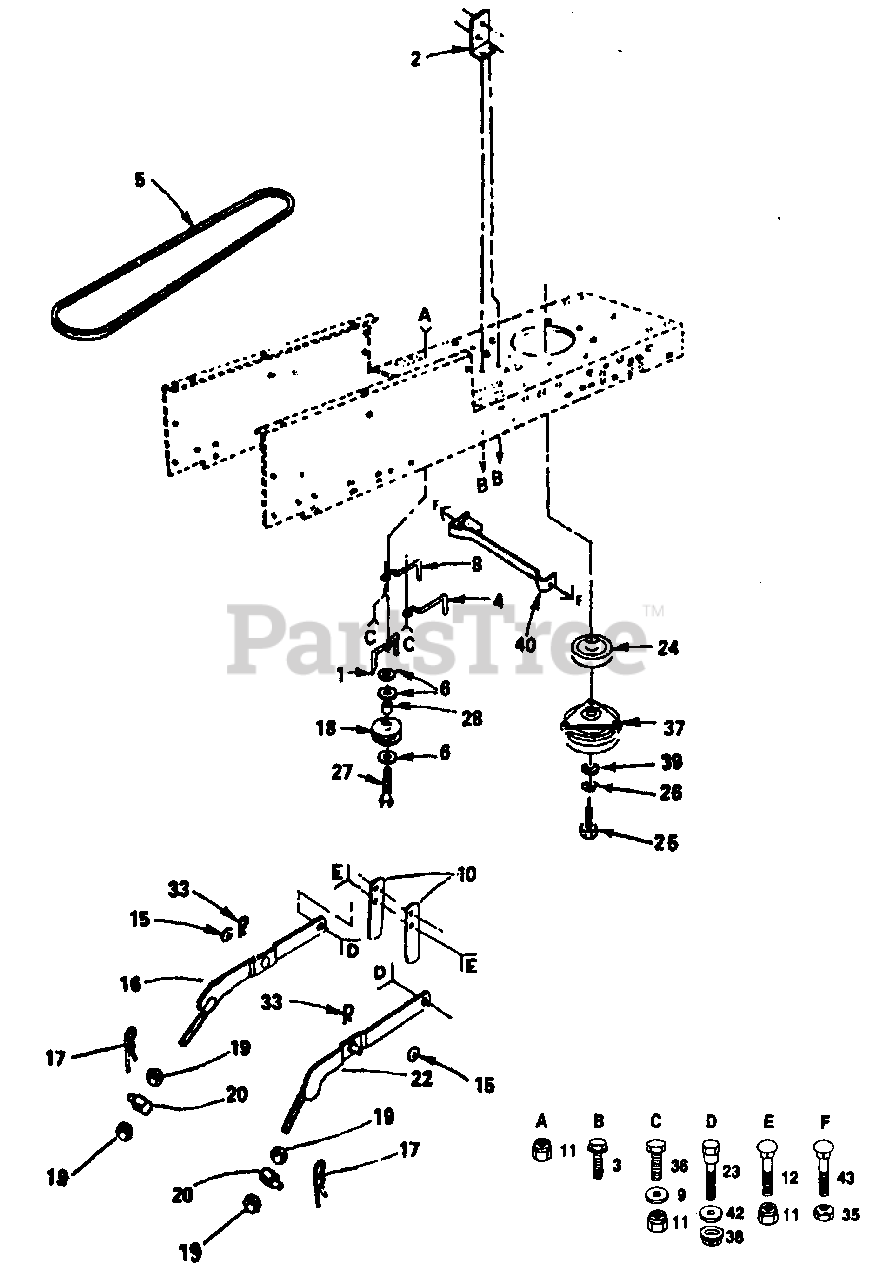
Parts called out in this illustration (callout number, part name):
1	Retainer, Belt (AYP part number)
2	Bracket, Switch (AYP part number)
3	Screw, Tapping, Hex Head #10-24 x 1/2 (AYP part number)
4	Keeper, Belt, Engine (AYP part number)
5	V-Belt, Drive (AYP part number)
6	Washer 13/32 x 13/16 x 16 Gauge (AYP part number)
8	Keeper, Belt, Engine (AYP part number)
9	Washer 13/32 x 13/16 x 12 Gauge (AYP part number)
10	Upstop, Mower (AYP part number)
11	Nut, Crownlock 3/8-16
12	Bolt, Carriage 3/8-16 x 1 (AYP part number)
15	Washer 17/32 x 15/16 x 16 Gauge (AYP part number)
16	Arm Assembly, Suspension, L.H. (AYP part number)
17	Retainer, Spring (AYP part number)
18	Idler, Flat (AYP part number)
19	Nut, Hex 1/2-13 (AYP part number)
20	Trunnion, Lift, Lower (AYP part number)
22	Arm Assembly, Suspension, R.H. (AYP part number)
23	Bolt, Shoulder 3/8-16 (AYP part number)
24	Pulley, Engine (AYP part number)
25	Bolt, Hex 7/16-20 x 4-1/4 Grade 8 (AYP part number)
26	Washer, Lock 7/16 (AYP part number)
27	Bolt, Hex 3/8-16 x 2-3/4 (AYP part number)
28	Spacer (AYP part number)
33	Spring, Retainer (AYP part number)
35	Locknut 5/16-18
36	Bolt, Hex 3/8-16 x 1 (AYP part number)
37	Clutch, Electric (AYP part number)
38	Nut, Centerlock, Flange 3/8-16 (AYP part number)
39	Washer 15/32 x 1-3/8 x 1/4 (AYP part number)
40	Locater, Clutch (AYP part number)
42	Washer, Spring (AYP part number)
43	Bolt, Carriage 5/16-18 x 3/4
